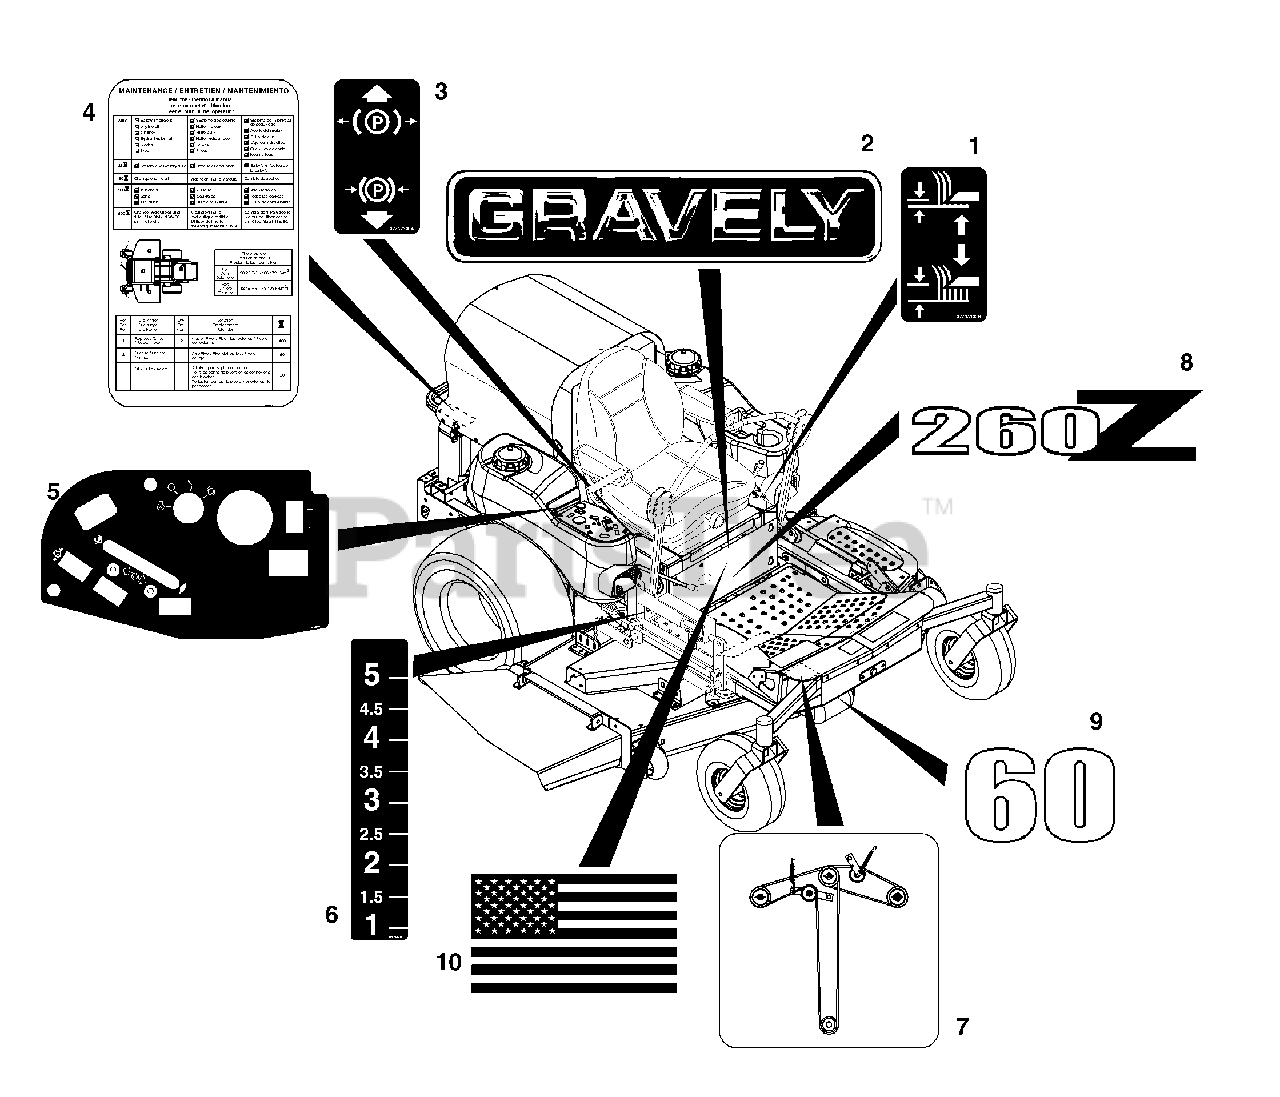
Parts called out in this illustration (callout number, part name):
1	Decal, Lift Lever
2	Decal, 15" Gravely Logo
3	Decal, Parking Brake Lever
4	Decal, Service Instructions
5	Decal, Diesel Control Panel (060, 061, 318, 319)
5	Decal, Control Panel (058, 059)
6	Decal, Height of Cut
7	Decal, Belt Diagram (058, 060, 318, 319)
7	Decal, Belt Diagram (059, 061)
8	Decal, PM-260Z (058, 060, 318, 319)
8	Decal, PM-272Z (059, 061)
9	Decal, 60 (058, 060, 318, 319)
9	Decal, 72 (059, 061)
10	Decal, American Flag
